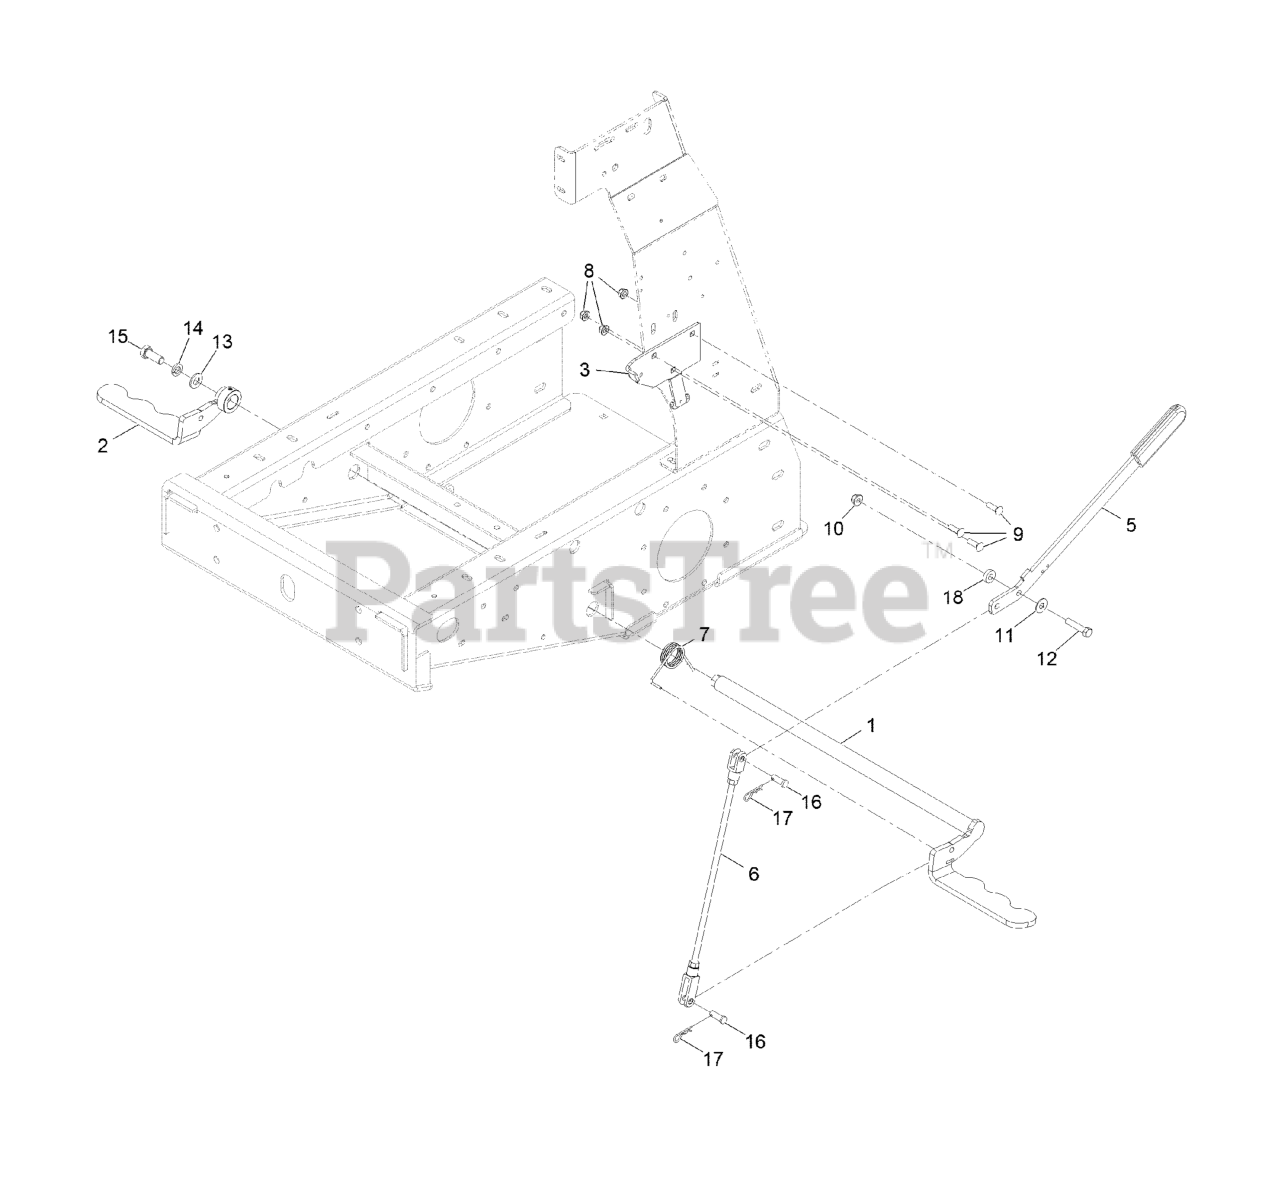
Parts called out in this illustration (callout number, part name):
1	Arm-Brake, Lt [black]
2	Arm-Brake, Rt [black]
3	Bracket-Handle, Brake
5	Handle-Brake
6	ASM, Rod-Brake
7	SPRING-TORSION
8	Nut-Hex Flange
9	Bolt,Carriage,5/16-18X1,ST/ST 18-8
10	NUT-HF, NI
11	WASHER-FLAT
12	SCREW-HH
13	WASHER-FLAT
14	WASHER-LOCK
15	Screw ( .50-20Unfx1.25 Grade 8]
16	PIN-CLEVIS
17	Pin-Hair
18	SPACER
